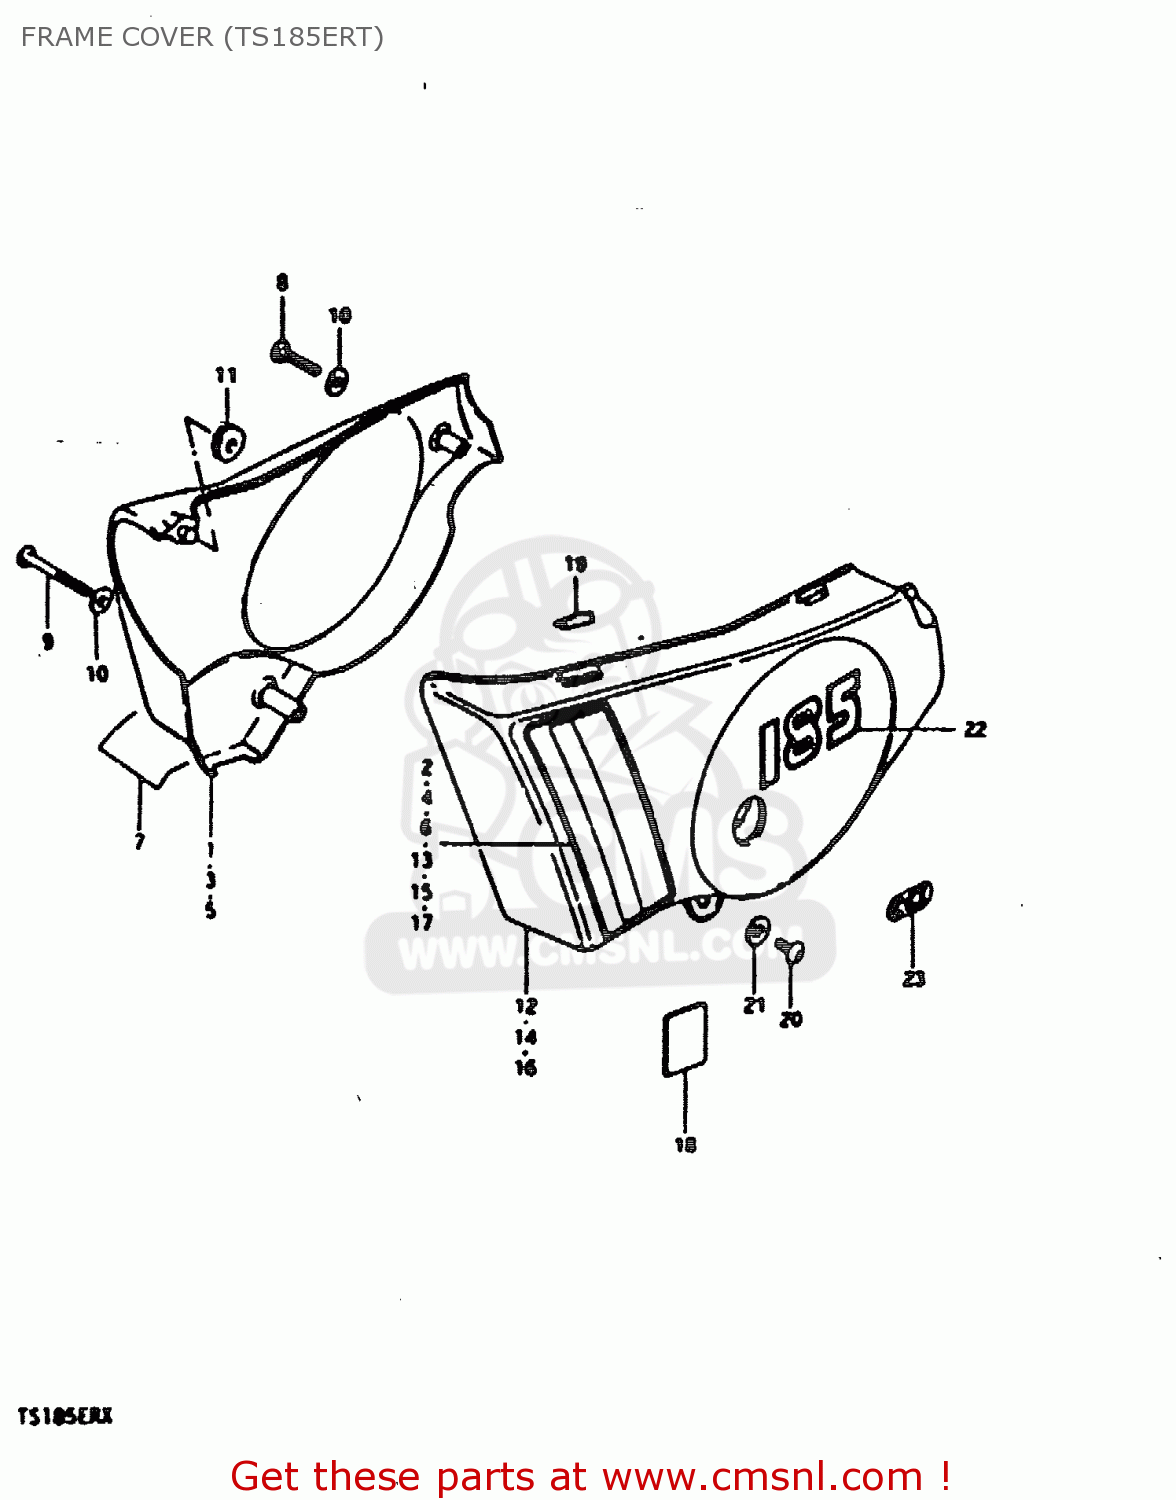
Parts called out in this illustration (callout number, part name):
1	COVER, FRAME RH (RED)
2	TAPE, RH
3	COVER,FRAME,RIGHT
4	TAPE, RH
5	COVER, FRAME RH (GREEN)
6	TAPE, RH
7	EMBLEM,FRAME COVER,RIGHT
8	SCREW
9	SCREW
10	WASHER
11	CUSHION
12	COVER, FRAME LH
13	TAPE, LH
14	COVER,FRAME,LEFT
15	TAPE, LH
16	COVER, FRAME LH
17	TAPE, LH
18	PROTECTOR(170X95X3.0)
19	CUSHION,FRAME COVER
20	SCREW 6X12
21	WASHER
22	EMBLEM "185"
23	EMBLEM,CCIS
